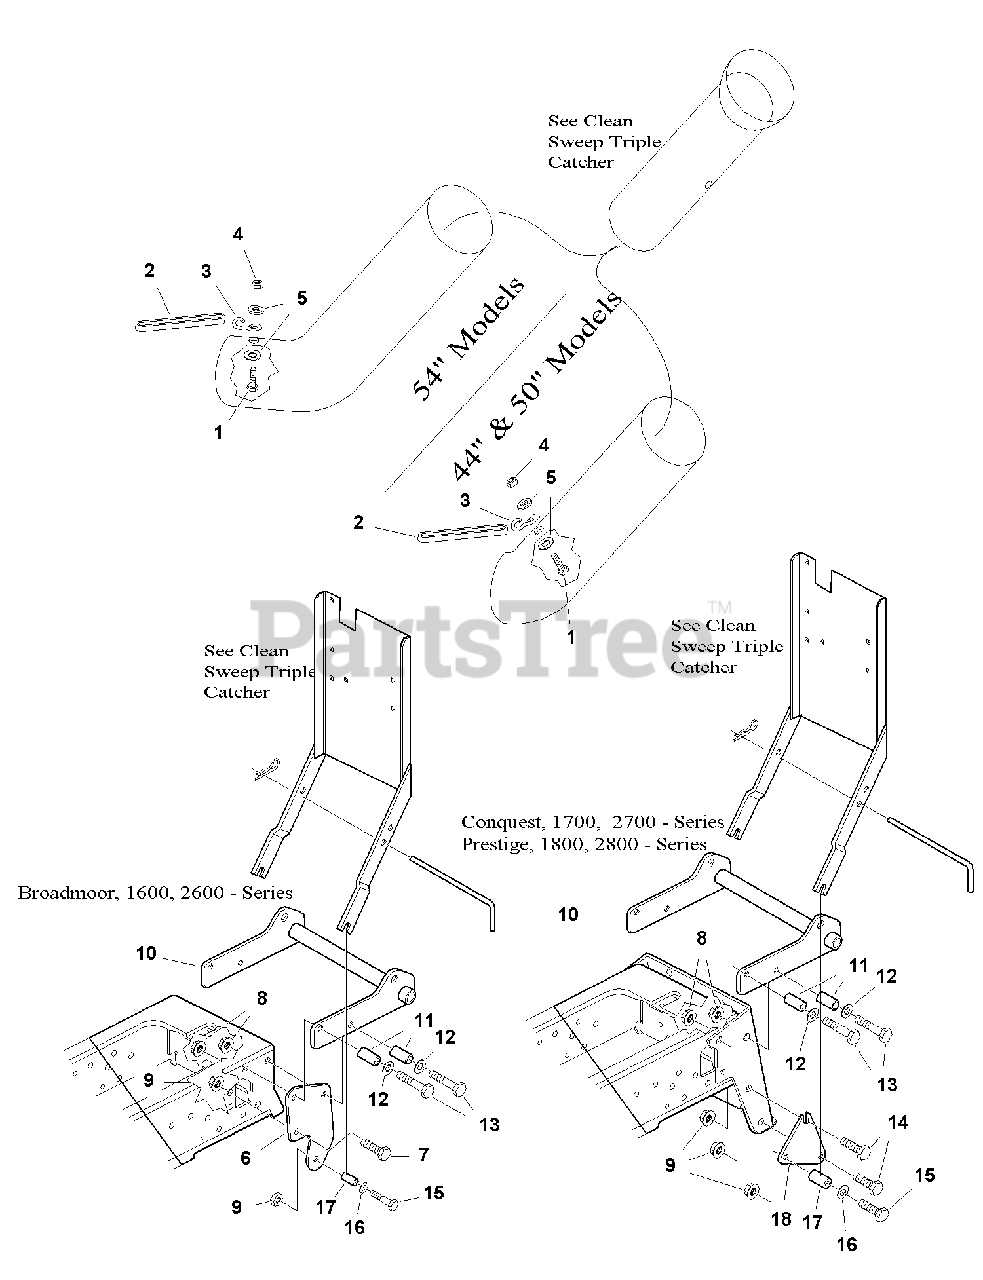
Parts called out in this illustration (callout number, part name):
1	CAPSCREW, Hex Head, 1/4-20 x 7/8
2	STRAP, Rubber, Black
3	HOOK
4	NUT, Hex Lock ESNA, 1/4-20
5	WASHER
6	PLATE, Slide
7	CAPSCREW, Hex Head, 3/8-16 x 1
8	NUT, Hex Lock ESNA, 1/2-13
9	NUT, Hex Flange Lock, 3/8-16
10	HITCH ASSEMBLY
12	WASHER
13	CAPSCREW, Hex Head, 1/2-13 x 3
14	CAPSCREW, Hex Head, 3/8-16 x 1-1/4
15	CAPSCREW, Hex Head, 3/8-16 x 2-1/4
17	SPACER
18	PLATE, Lower
